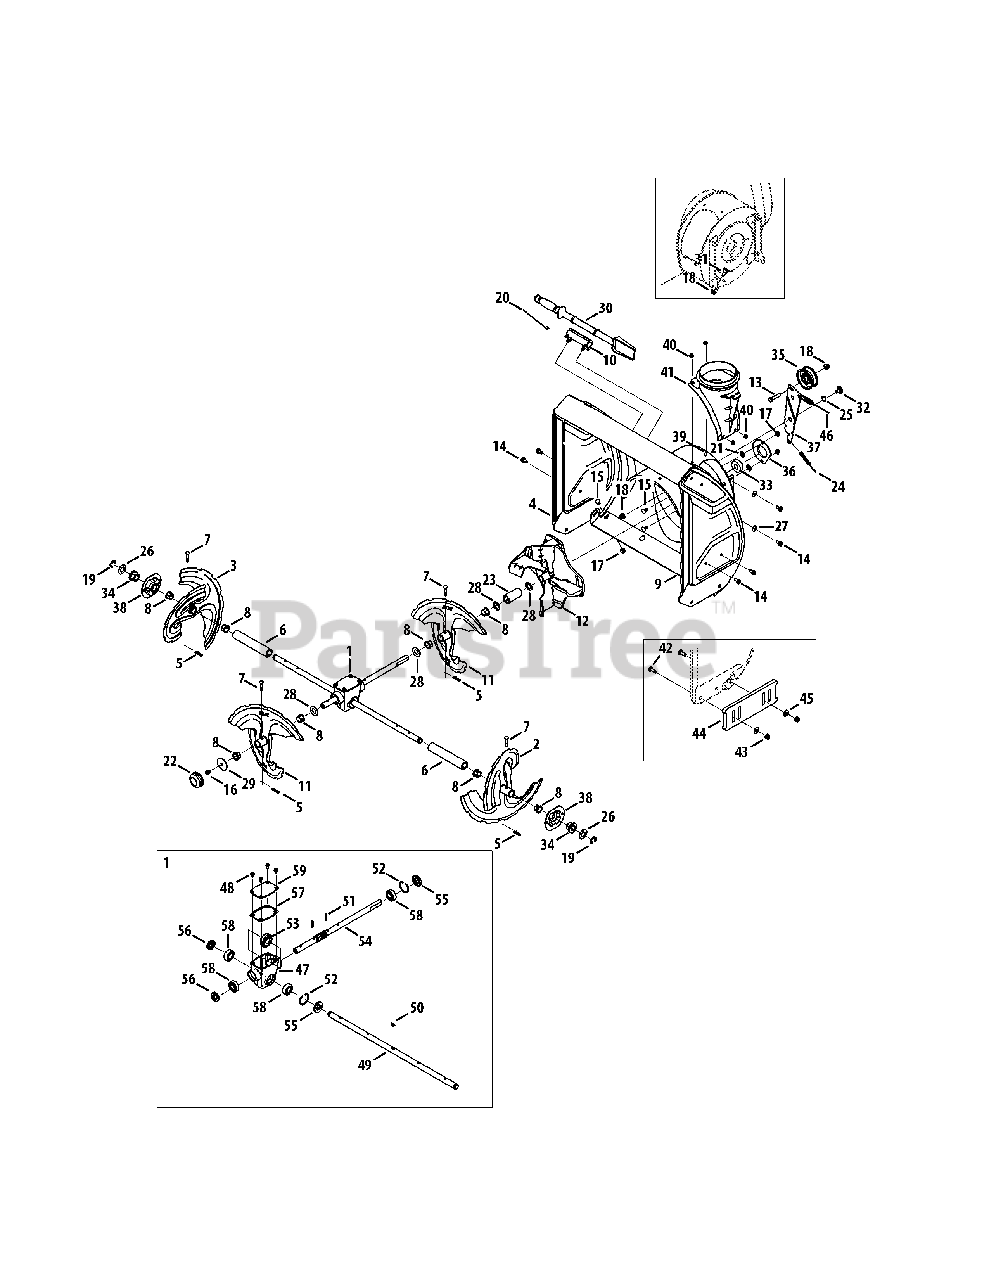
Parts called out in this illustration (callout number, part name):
1	Gearbox Assembly, Auger, 26"
2	Spiral Assembly - LH
3	Spiral Assembly - RH
4	Auger Housing, 26"
5	Bow Tie Cotter Pin
6	Spacer, 1.25 OD x .75 ID x 6.83
8	Flange Bushing, .800 x .910
9	Shave Plate, 26"
10	Clean-out Tool Mtg. Bracket
11	Accelerator Assembly
12	Impeller Assembly
13	Hex Bolt, 3/8-16 x 1.75
14	Screw, 5/16-18 x .750
15	Carriage Bolt, 5/16-18 x .750
16	Hex Washer Screw, 5/16-18 x .500
17	Flange Lock Nut, 5/16-18
18	Flange Lock Nut, 3/8-16
19	E-ring, .75
20	Cable Tie
21	Push-On Nut, .25 Dia.
23	Spacer, 1.25 OD x .75 ID x 2.61
24	Extension Spring, .38 OD x 4.59
25	Wave Washer, .625 x .885 x .0175
26	Flat Washer, .76 x 1.49 x .06
27	Bell Washer, .340 x .872 x .060
28	Flat Washer, .793 x 1.24 x .06
29	Flat Washer, .406 x 1.92 x .060
30	Clean-Out Tool
31	Shoulder Screw, 3/8-16 x .496 x .336
32	Shoulder Screw, 3/8-16 x .625 x .17
33	Flange Ball Bearing, .75 x 1.85
34	Hex Flange Bearing, .75 ID
35	Flat Idler Pulley
36	Bearing Housing
37	Auger Idler Bracket
38	Bearing Housing
39	Carriage Screw, 1/4-20 x 0.75
40	Flange Lock Nut, 1/4-20
41	Chute Adapter
42	Spacer, Carriage, 5/16-18 x 1.00
43	Hex Lock Nut, 5/16-18
44	Deluxe Slide Shoe
45	Washer, Flat, .349 x .879 x .063
46	Auger Clutch Cable
47	Auger Housing
48	Screw, 1/4-20 x 0.75
49	Axle, Auger, 26"
50	Hi-Pro Key
51	Pin, Roll, .25 x 1.0
52	Retainer Ring
53	Worm Gear, 20T
54	Worm Shaft
55	Seal, .75 x 40mm x .25
56	Seal, .75 x 1.375 x .25
57	Gearbox Gasket
58	Ball Bearing, .75 x 40 x 12
59	Gearbox Cover
